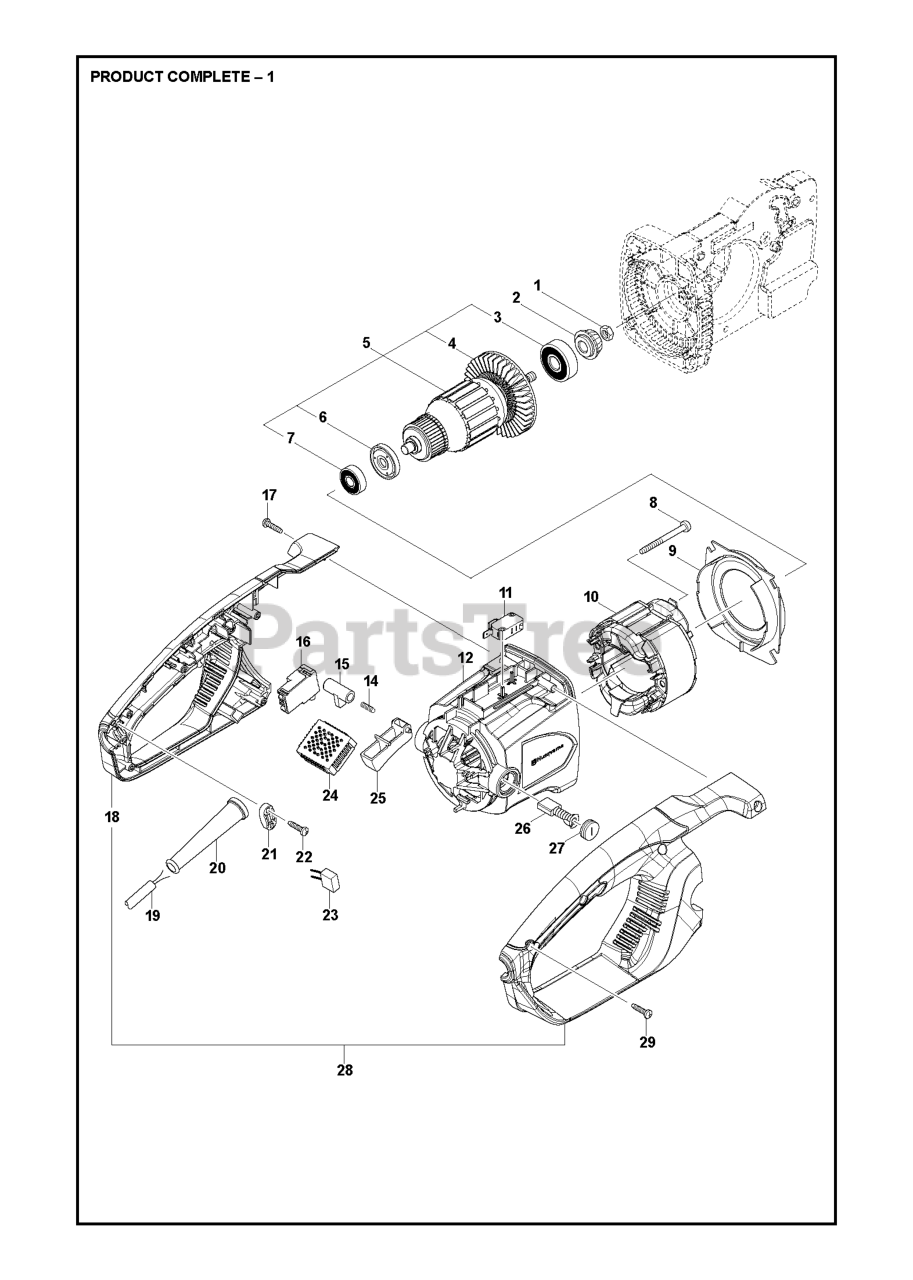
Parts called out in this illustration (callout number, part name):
31	COVER PART FOR 414EL/418EL/420
32	SEAL PART FOR 414EL/418EL/420E
34	CONNECTOR PART FOR 414EL/418EL
35	CONNECTOR PART FOR 414EL/418EL
36	BEVEL GEAR PART FOR 414EL/418E
37	CAP PART FOR 414EL/418EL/420EL
38	ROD PART FOR 414EL/418EL/420EL
39	COMPRESSION SPRING PART FOR 41
41	PLATE PART FOR 414EL/418EL/420
42	COMPRESSION SPRING PART FOR 41
43	O-RING PART FOR 414EL/418EL/42
44	GEAR HOUSING PART FOR 414EL/41
45	SCREW PART FOR 414EL/418EL/420
46	BALL BEARING PART FOR 414EL/41
47	RING PART FOR 414EL/418EL/420E
48	WORM GEAR PART FOR 414EL/418EL
49	OIL PUMP PART FOR 414EL/418EL/
50	GROMMET PART FOR 414EL/418EL/4
51	SCREW PART FOR 414EL/418EL/420
52	BEVEL GEAR PART FOR 414EL/418E
53	SPINDLE PART FOR 414EL/418EL/4
54	BALL BEARING PART FOR 414EL/41
55	FRONT HANDLE PART FOR 414EL/41
56	SCREW PART FOR 414EL/418EL/420
57	BUMPER PART FOR 414EL/418EL/42
58	SCREW PART FOR 414EL/418EL/420
59	BEARING HOUSING PART FOR 414EL
60	SCREW PART FOR 414EL/418EL/420
61	WASHER PART FOR 414EL/418EL/42
62	SCREW PART FOR 414EL/418EL/420
63	BRAKE BAND PART FOR 414EL/418E
64	BRAKE DRUM PART FOR 414EL/418E
65	WASHER PART FOR 414EL/418EL/42
66	RING PART FOR 414EL/418EL/420E
67	SCREW PART FOR 414EL/418EL/420
68	COVER PART FOR 414EL/418EL/420
69	BEVEL GEAR PART FOR 414EL/418E
70	ADJUST SCREW
71	PIN PART FOR 414EL/418EL/420EL
72	SCREW PART FOR 414EL/418EL/420
75	PIN PART FOR 414EL/418EL/420EL
76	GEAR PART FOR 414EL/418EL/420E
77	COVER PART FOR 414EL/418EL/420
78	NUT CAP PART FOR 414EL/418EL/4
81	HOSE CLAMP PART FOR 414EL/418E
